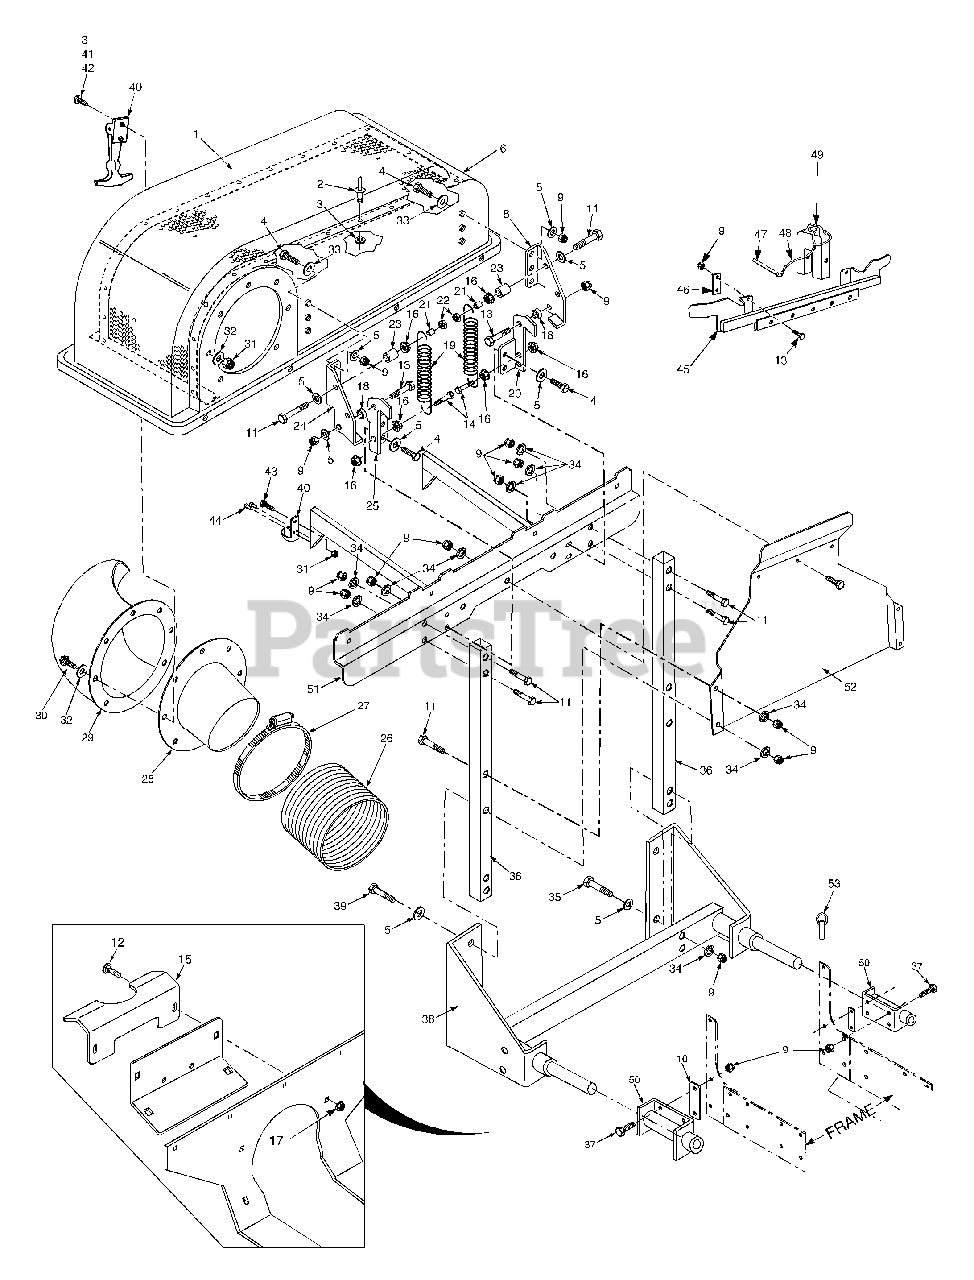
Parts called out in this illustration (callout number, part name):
1	Screen, Catcher Hood
2	Pop Rivet, 3/16 x .652
3	Flatwasher, 3/16-.196 x .469 x .048
4	Bolt, Hex Head 3/8-16 x 1-1/4"
5	Flatwasher, 3/8-.391 x .938 x .105
6	Hood Assembly, GC-STT
7	Bolt, Hex Head 3/8-16 x 2-3/4"
8	Hinge, Upper LH
9	Nut, Elastic Stop 3/8-16
10	Spacer, Hitch
11	Bolt, Hex Head 3/8-16 x 2-1/4"
12	Bolt, Carriage 5/16-18 x 1.00
13	Bolt, Hex Head 3/8-16 x 1-1/2"
14	Bolt, Hex Head 3/8-16 x 1-3/4" Grade 8
15	Support Bracket, Catcher
16	Nut, Serrated Flange 3/8-16
17	Nut, Hex Serrated Flange 5/16-18
18	Bushing, Hopper Pivot
19	Spring, Hood Hinge
20	Hinge, Lower LH
21	Spacer
22	Locknut, 3/8-16
23	Spacer
24	Hinge, Upper RH
25	Hinge, Lower RH
26	Hose, 8" Dia. x 60.5"
27	Clamp, 8-5/8" Max Dia.
28	Tube, Filler GC-STT
29	Elbow, GC-STT
30	Bolt, Hex Head 5/16-18 x 1-1/4"
31	Nut, Elastic Stop 5/16-18
32	Flatwasher, 5/16-.375 x .875 x .083
33	Flatwasher, 3/8- .406 x 1-1/2" x .179
34	Lockwasher, 3/8 Spring
35	Bolt, Hex Head 3/8-16 x 3-3/4"
36	Tube, Upright
37	Bolt, Hex Head 3/8-16 x 1"
38	Frame Weldment
39	Bolt, Hex Head 3/8-16 x 2-1/2"
40	Latch
41	Screw, #10-32 x 3/4"
42	Nut, Elastic Stop #10-32
43	Bolt, Hex Head 5/16-18 x 3/4"
44	Rivet, 3/16 x .402 POP
45	Support Weldment, Front Weights
46	Clamp, Bar
47	Pin, 1/2 x 6-1/4"
48	Lanyard, Weight Pin
49	Weight Assembly
50	Hitch Bracket Weldment
51	Support Weldment, Bag Frame
52	Heat Shield
53	Quick Pin
